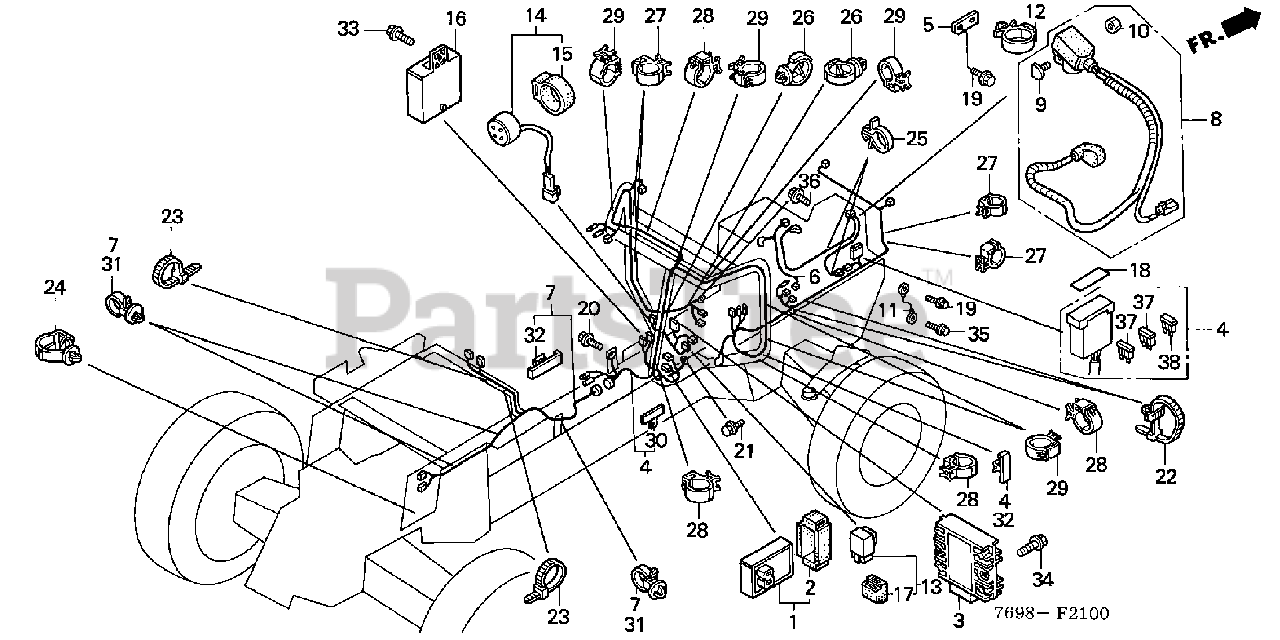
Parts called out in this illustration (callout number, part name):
1	MODULE, IGNITION CONTROL (CDI)
2	CUSHION, IGNITION CONTROL MODULE
3	RECTIFIER, REGULATOR
4	WIRE HARNESS ASSY., MAIN
5	BRACKET, WIRE HARNESS CLIP
6	WIRE HARNESS ASSY., ENGINE
7	WIRE HARNESS ASSY., RR.
8	CABLE ASSY., STARTER
9	BOLT, BATTERY TERMINAL (SUMITOMO)
10	NUT, BATTERY TERMINAL (SUMITOMO)
11	CABLE, SUB-GROUND
12	CLAMP, ENGINE SUB-WIRE
13	RELAY ASSY., CONTROL (20A)
14	BUZZER ASSY., WARNING
15	SUSPENSION, AUDIBLE PILOT
16	RELAY ASSY., COMBINATION
17	SUSPENSION, STARTER RELAY (TATEISHI)
18	LABEL, FUSE (ENGLISH)
19	BOLT, FLANGE (6X14)
20	BOLT, GROUND (6X16) (SN)
21	BOLT, GROUND (6X12) (SN)
22	BAND, WIRE HARNESS (WHITE)
23	BAND, CABLE (120MM) (BLACK)
24	CLIP, WIRE HARNESS
25	CLIP, WIRE HARNESS
26	CLIP, WIRE HARNESS (25MM)
27	CLIP, CABLE (10MM)
28	CLIP, CABLE (15MM)
29	CLIP, CABLE (20MM)
30	CLIP, WIRE HARNESS
31	BAND, WIRE HARNESS (110MM) (BROWN)
32	CLIP, WIRE HARNESS (BLACK)
33	BOLT, FLANGE (6X14)
34	BOLT, FLANGE (6X22)
35	BOLT, FLANGE (8X12)
36	BOLT, FLANGE (8X16)
37	FUSE, BLADE (5A)
38	FUSE, BLADE (20A)
